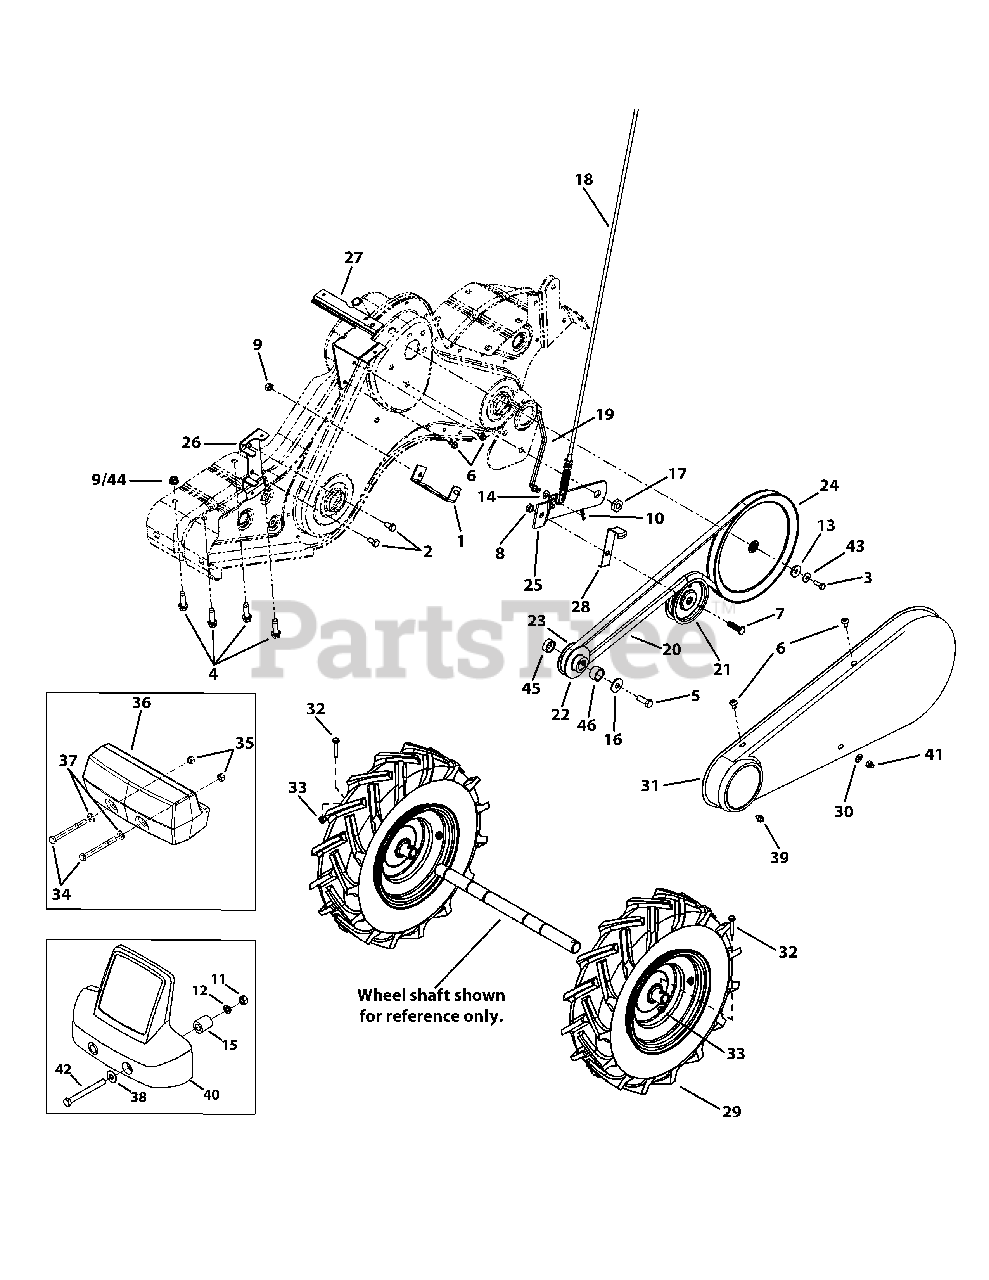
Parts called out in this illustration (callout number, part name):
1	Belt Cover Bracket Assembly
2	Hex Bolt, 5/16-24 x .625
3	Hex Bolt, 1/4-28 x .75"
4	SEMS Screw, 3/8-16 (MTD Engine)
5	Hex Bolt, 3/8-24 x 1.0
6	Hex Washer Screw
7	Hex Cap Screw, 3/8-16 x 1.25
8	Lock Jam Nut, 3/8-16
9	Flangelock Nut, 5/16-18
10	Internal Cotter Pin
11	Hex Nut, 1/2-20
12	Washer, Lock, 1/2
13	Flat Washer, .25 ID x .93 OD
14	Spring Washer, .317 ID x .625 OD
15	Hub, .636 ID x 1.00 OD x .94
16	Bell Washer, .396 ID x 1.14 OD
17	Shoulder Nut, 7/16-20
18	Clutch Cable
19	Idler Pulley Rod
21	Flat Idler w/ Flange, 3.75 OD
22	Outer Engine Pulley Half
23	Inner Engine Pulley Half
24	Input Pulley
25	Idler Bracket
26	Belt Keeper Bracket
27	Shift Cover Bracket
28	Idler Belt Keeper
29	Wheel Assembly, 16.0 x 4.6 x 8
30	Flat Washer, .271 ID x .630 OD
31	Belt Cover
32	Hex Head Screw, 1/4-20
33	Flange Lock Nut, 1/4-20
34	Hex Bolt, 1/2-13 x 5.0
35	Flange Lock Nut, 1/2-13
36	Counterweight, 40 lbs.
37	Flat Washer
38	Washer, Flat, 1/2 x 1.25 x .100
39	Hex Screw, 1/4-20 x .375
40	Counterweight
42	Hex Head Screw, 1/2-13 x 5.50
43	Bell Washer, .265 x .750 x .060
44	Flangelock Nut, 3/8-16
45	Spacer, .766 ID X 1.25 OD X .415 (Kohler)
46	Spacer, 19.5 ID x 25.0 OD x 14.5 (Kohler)
